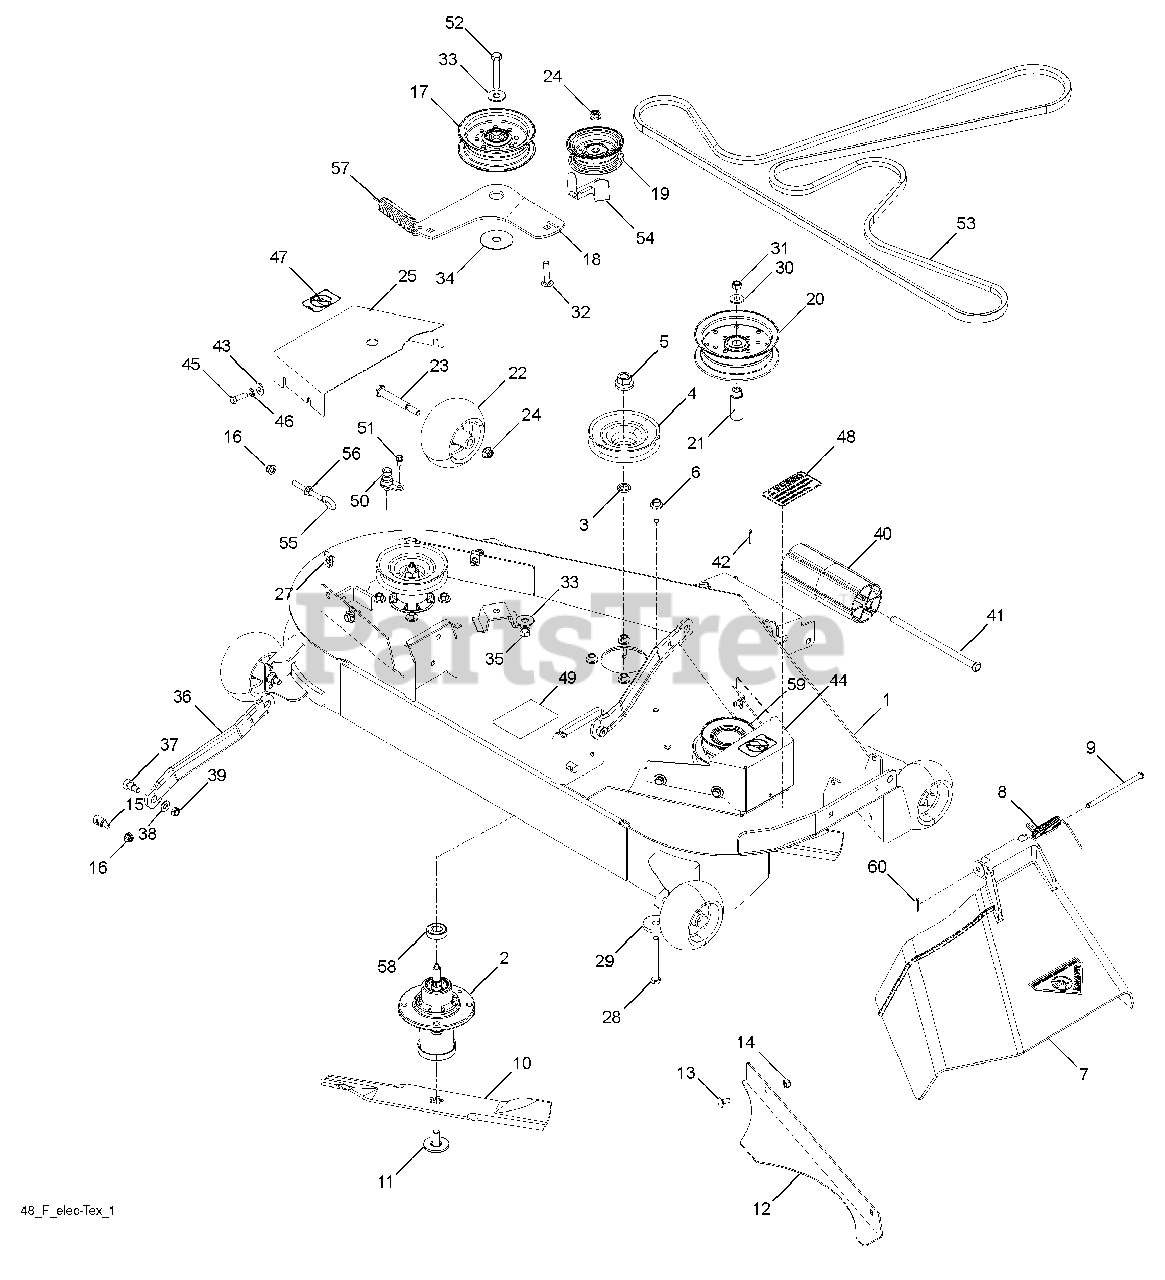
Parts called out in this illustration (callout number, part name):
1	Deck w/ Decals 48"
2	Housing Assembly
3	Washer-Spacer
4	Pulley, Mandrel
5	Nut, 9/16 Top Center Lock
6	Screw, Washer Head
7	Discharge Chute, 48"
8	Spring - Torsion
9	Pin, Clevis 5/16 x 5.19
10	Blade, 16-1/4"
11	Bolt, 7/16, Assy Blade
12	Confinement Plate
13	Rhsnb 5/16-18 x 5/8 Gr 5
14	Nut 5/16-18 Hex Nyloc
15	Stud, Fasten w/ Anti- Rotate
16	Nut 5/16-18 Hex Flange Nyloc
17	Pulley, Idler Spec. Hub
18	Arm, Idler, Blk
19	Pulley, Idler
20	Pulley, Idler
21	Idler Bushing
22	Wheel, Gauge
23	Bolt, Shoulder
24	Nut 3/8-16 Hex Flg Nyloc
25	Shield, Belt LH
27	Retainer 5/16c U Type
28	Hcs 3/8-16 x 3-1/2 Gr 5
29	Heavy Washer
30	Washer, 3/8 Flat Std
31	Nut 3/8-16 Hex Nyloc
32	Rhsnb 3/8-16 x 1-3/4 Gr 5
33	Washer, 7/16 Flat
34	Washer, Flat Hardened
35	Nut, 7/16-14 Hex Nyloc
36	Arm, Susp., Rear
37	Sb 3/8-16 x 3/8 Skt Hd
38	Washer, 3/8 Sae Flt
39	Nut, 3/8-16 Hex Jam Nyloc
40	Roller, Nose, 48"
41	Rod, Roller, Nose, Narrow
42	Pin Cotter 5/16 Bow Tie Lock
43	Washer, 5/16 Std Flt
44	Shield, Belt Rh
45	Hcs 5/16-18 x 1 Gr 5
46	Wash 5/16 Slw
47	Decal, No Step
48	Decal, Warning
49	Decal, Deck Sch
50	Washout Port
51	Bolt, 1/4-20 x 1/2
52	Hcs 7/16-14 x 2-1/2 Gr 5
53	Belt, Deck
54	Guard, Belt
55	Eyebolt 5/16 x 3-1/2
56	Nut 5/16-18 Hex Whizlk
58	Ball Bearing
59	Pulley
60	Clip Retainer
